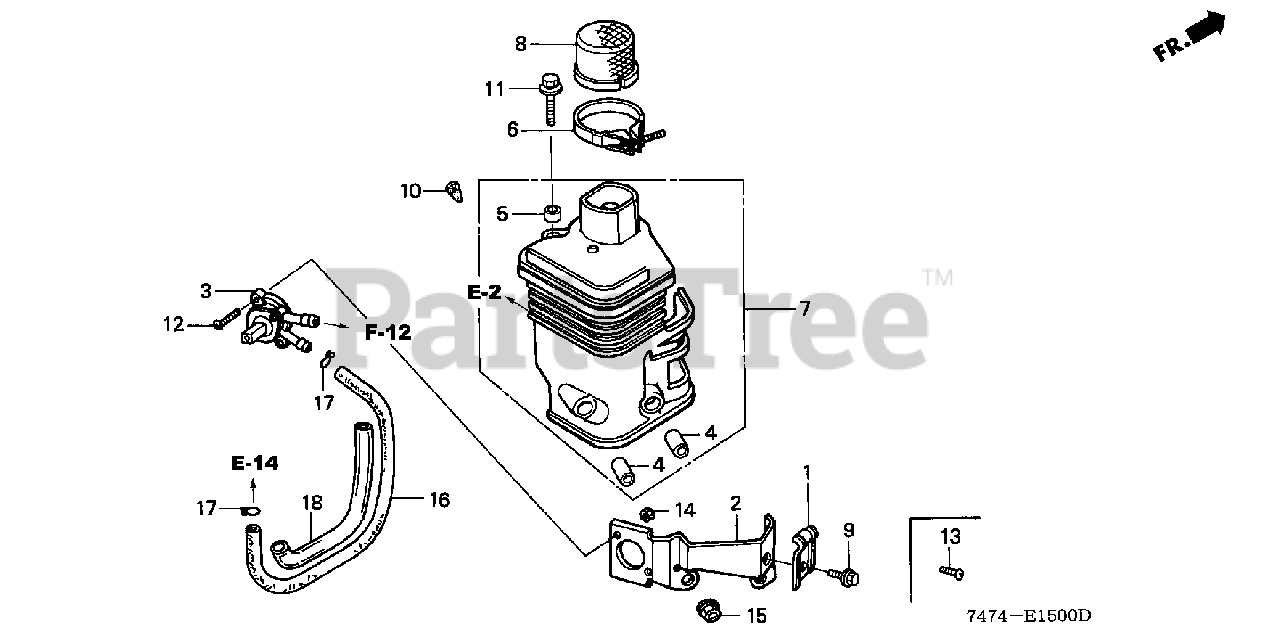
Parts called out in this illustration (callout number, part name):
1	HOLDER, CONTROL CABLE
2	STAY, CHOKE CONTROL
3	PETCOCK ASSY.
4	COLLAR, AIR CLEANER
5	COLLAR B, AIR CLEANER
7	ELBOW, AIR CLEANER
9	BOLT, FLANGE (5X10)
10	PLUG, CONE TYPE
11	BOLT, FLANGE (6X20)
12	SCREW, PAN (3X12)
14	NUT, HEX. (3MM)
15	NUT, FLANGE (6MM)
16	BULK HOSE, FUEL (5.5X3000) (5.5X220)
17	CLIP, TUBE (B10)
18	BULK HOSE, VINYL (11X13X3000) (11X180)
